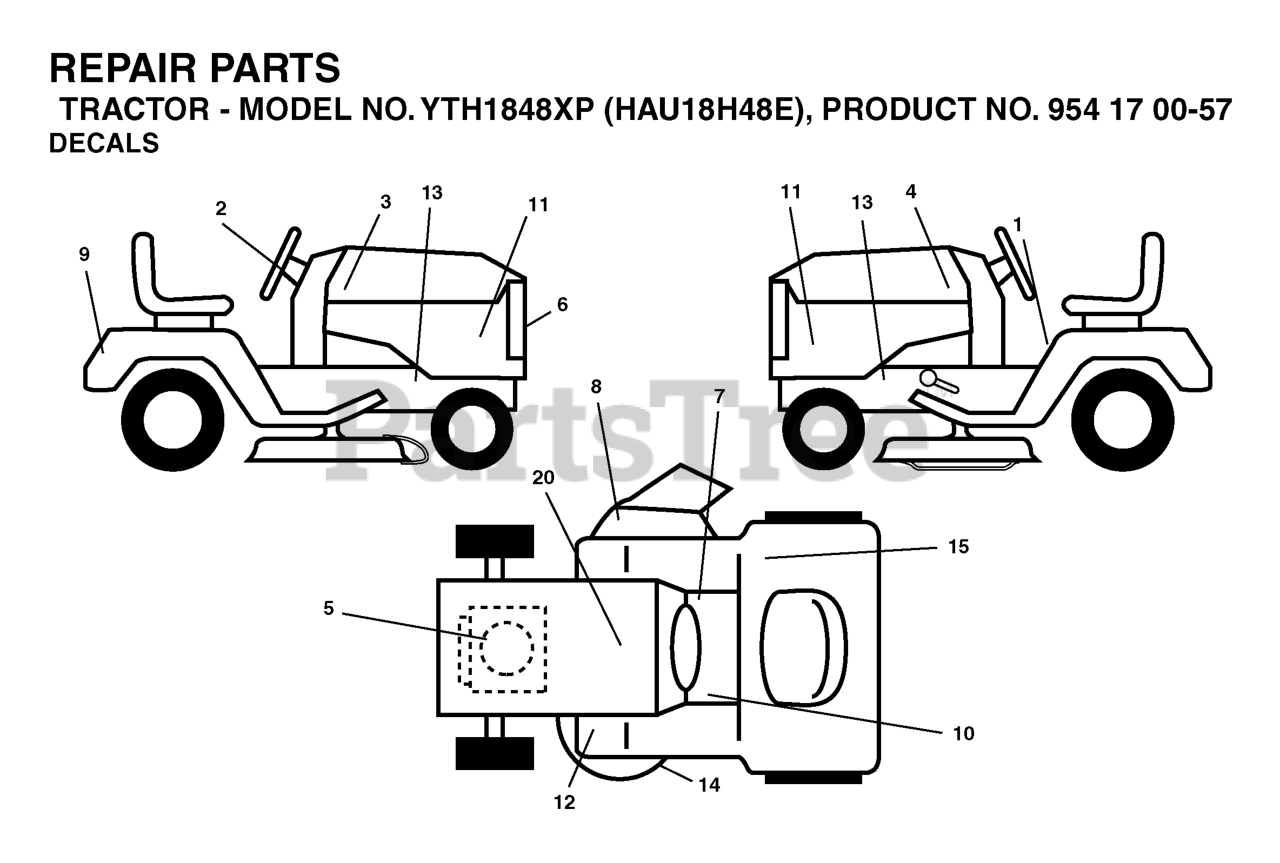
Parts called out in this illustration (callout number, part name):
1	DECAL READ OWNER'S MAN SYMS
2	DECAL.WHEEL.STEERING.HUSQ.PERM
3	HOOD DECAL
4	HOOD DECAL
5	DECAL ENGINE
6	DECAL.GRILLE.HUSQ
7	DECAL PARK BRAKE
8	DECAL.INTERNATIONL.CUTFINGER
9	DECAL, FENDER
10	DECAL
11	DECAL HOOD
12	DECAL CLUTCH/BRAKE
14	DECAL V-BELT SCHEMATIC
15	DECAL
20	DECAL BTRY SYMBOLS
